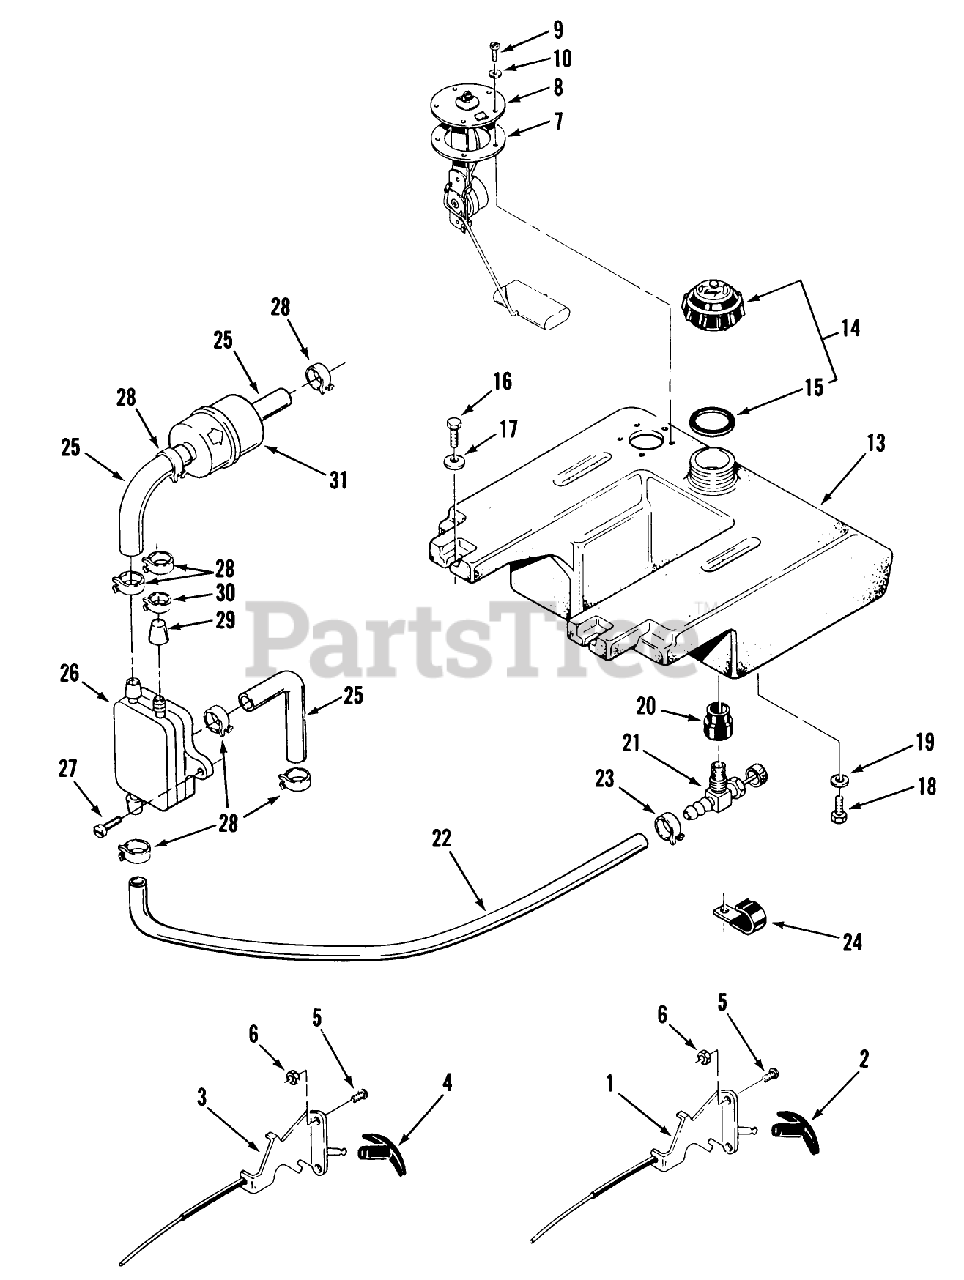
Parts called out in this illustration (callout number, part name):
1	CONTROL-THROTTLE
2	KNOB-THROTTLE
3	CONTROL-CHOKE
4	KNOB-CHOKE
5	SCREW-PPH
7	GASKET-SENDER, FUEL
14	ASS'Y-GAS CAP
21	VALVE-FUEL
24	CLAMP
